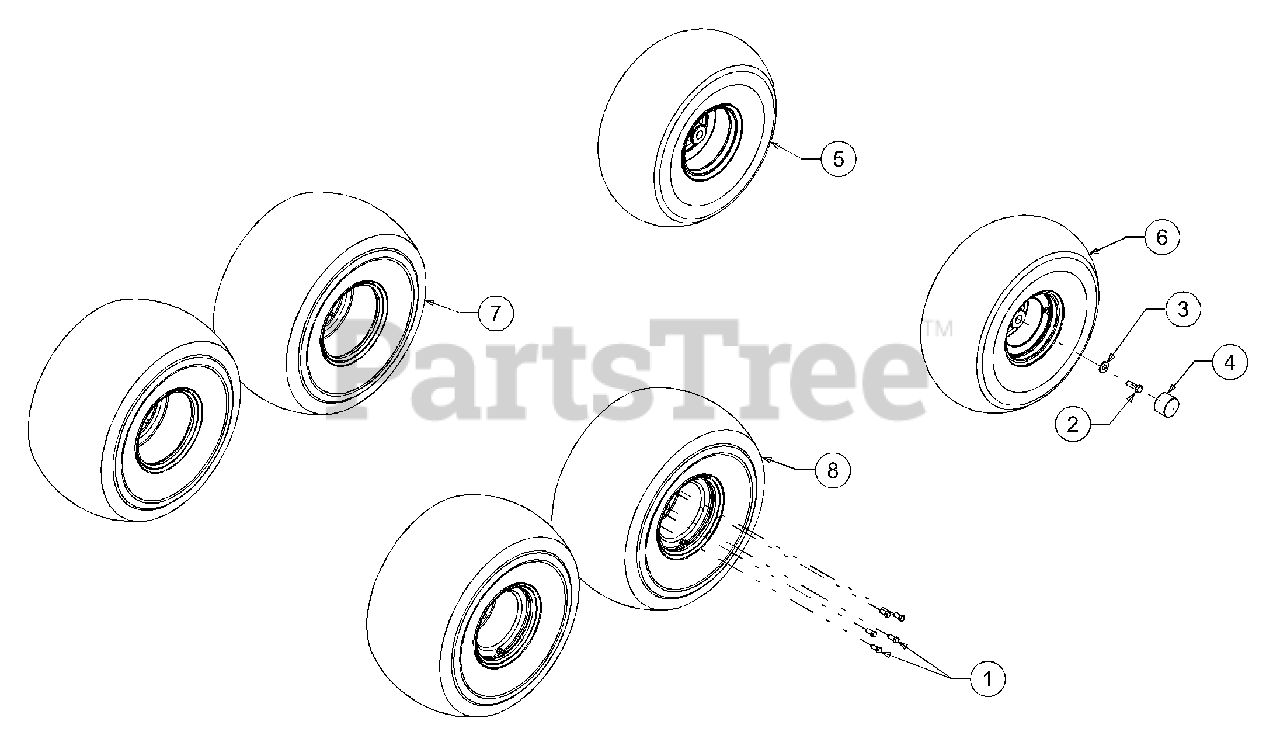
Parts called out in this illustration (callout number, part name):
1	Hex Screw, 7/16-20 x 1.5, Gr5
2	Hex Screw, 1/2-13 x 1.5, Gr5
3	Washer, Flat, .531 x 1.25 x .181
4	Dust Cover
5	Wheel Ass'y, 22 x 11 x 10 LH (All Terrain)
5	Wheel Ass'y, 22.5 x 10 x 8 (Knobby)
5	Wheel Ass'y, 22 x 12 x 8 (Heavy Duty)
5	Wheel Ass'y, 22.5 x 10 x 8 (Turf)
6	Wheel Ass'y, 22 x 11 x 10 RH (All Terrain)
6	Wheel Ass'y, 22.5 x 10 x 8 (Knobby)
6	Wheel Ass'y, 22 x 12 x 8 (Heavy Duty)
6	Wheel Ass'y, 22.5 x 10 x 8 (Turf)
7	Wheel Ass'y, 25 x 11 x 10 LH (All Terrain)
7	Wheel Ass'y, 25 x 12 x 9 (Knobby)
7	Wheel Ass'y, 25 x 13 x 9 (Heavy Duty)
7	Wheel Ass'y, 25 x 12 x 9 (Turf)
8	Wheel Ass'y, 25 x 11 x 10 RH(All Terrain)
8	Wheel Ass'y, 25 x 12 x 9 (Knobby)
8	Wheel Ass'y, 25 x 13 x 9 (Heavy Duty)
8	Wheel Ass'y, 25 x 12 x 9 (Turf)
